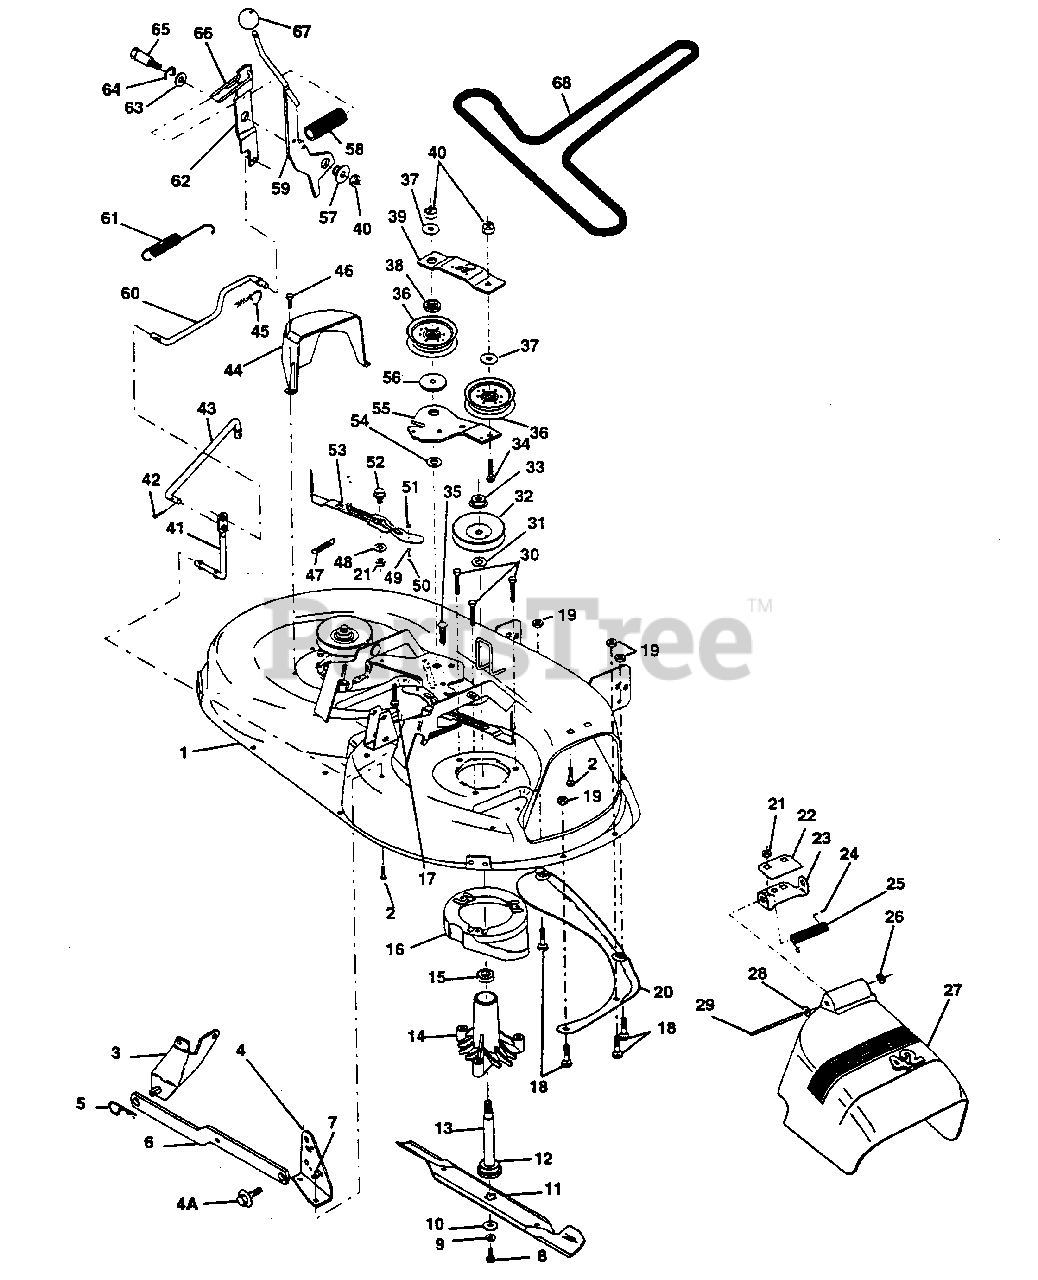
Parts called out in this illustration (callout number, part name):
1	Mower Housing (AYP part number)
2	Bolt Rdhd Sqnk 5/16-18unc X3/4
3	Bracket Asm Fr Sway Bar 38/42 (AYP part number)
4	Bracket Asm Deck 42"sway Bar (AYP part number)
5	Retainer Spring (AYP part number)
6	Arm Suspension Rear (AYP part number)
7	Locknut-hex W/ins 5/16-18unc P (AYP part number)
8	Bolt 3/8 - 24 X 1.25 Gr 8 (AYP part number)
9	Washer Lock Hvy 3/8 (AYP part number)
10	Washer Hard Blade Mower Vented (AYP part number)
11	Blade Mower High Perf 42"
12	Bearing Ball #6024 (Mandrel) (AYP part number)
13	Shaft Asm W/lower Bearing
14	Housing Mandrel Vented
15	Bearing Ball Mandrel (AYP part number)
16	Stripper Mower Vented (AYP part number)
17	Bolt Rdhd Sqnk 3/8-16 X 2-1/4 (AYP part number)
18	Bolt Rdhd Sqnk 5/16-18 X 5/8 (AYP part number)
19	Locknut-hex W/ins 5/16-18unc P (AYP part number)
20	Baffle Vortex 42 (AYP part number)
21	Nut Crown Lock 5/16-18
22	Stiffener Bracket 42"deck (AYP part number)
23	Bracket Deflector Mower 42" (AYP part number)
24	Cap Sleeve 80x 112 Blk Mower (AYP part number)
25	Spring Torsion Deflector 2 52 (AYP part number)
26	Nut Push Phos & Oil (AYP part number)
27	Shield Deflector Mower 42" Blk (AYP part number)
28	Washer 11/32 X 5/8 X 16 Ga (AYP part number)
29	Rod Hinge 42"6 75 Wlg (AYP part number)
30	Bolt 5/16-18 X 1 25 T/t (AYP part number)
31	Washer Spacer Mower Vented (AYP part number)
32	Pulley Mandrel 42" (AYP part number)
33	Nut 9/16 Toplock Flng Oil Dip
34	Bolt Rdhd 3/8-16uncx1-3/4 Gr5 (AYP part number)
35	Fastner Christmas Tree (AYP part number)
36	Pulley Idler Flat 3 060 (AYP part number)
37	Washer 13/32 X 1 X 12 Ga (AYP part number)
38	Spacer Arm Idler Upper Hdn 42" (AYP part number)
39	Stiffener Arm Idler Upper 42" (AYP part number)
40	Nut Crownlock 3/8-16 Unc
41	Rod Pivot W/nibs (AYP part number)
42	Pin Cotter 3/32 X 3/4 Cad (AYP part number)
43	Rod Clutch Secondary W/nibs (AYP part number)
44	Guard Mandrel LH Black (AYP part number)
45	Spring Retainer 1" Zinc/cad (AYP part number)
46	Screw Thdrol 1/4-20x5/8 T (AYP part number)
47	Spring Extension (AYP part number)
48	Washer Hardened Smaller (AYP part number)
49	Roller Asm Cam Follower 42"dec (AYP part number)
50	Bolt Shldr 10-24 Zinc Gr 5 42" (AYP part number)
51	Nut Lock #10-24 Unc (AYP part number)
52	Bolt Shoulder 5/16-18 Unc Blkz (AYP part number)
53	Arm Asm Pad Brake (AYP part number)
54	Washer Hardened (AYP part number)
55	Arm Idler 42"mower LT/YT (AYP part number)
56	Spacer Retainer Pm Mower (AYP part number)
57	Bushing 747 Od X 794 Lg Brass (AYP part number)
58	Spring Clutch Mower 2 750 Zinc (AYP part number)
59	Arm Asm Clutch Primary (AYP part number)
60	Rod Clutch Primary 38/42 (AYP part number)
61	Spring Return (AYP part number)
62	Arm Clutch Secondary (AYP part number)
63	Washer 25/32 X 1-5/8 X 16 Ga (AYP part number)
64	Ring Klip #t5304-75 (AYP part number)
65	Bolt Shoulder 3/8-16 Unc 1 44 (AYP part number)
66	Keeper Spring 4 000 (AYP part number)
67	Knob Rd 3/8-16 Plstc Thds Blk (AYP part number)
68	V-Belt Mower 42" 92 40 (AYP part number)
